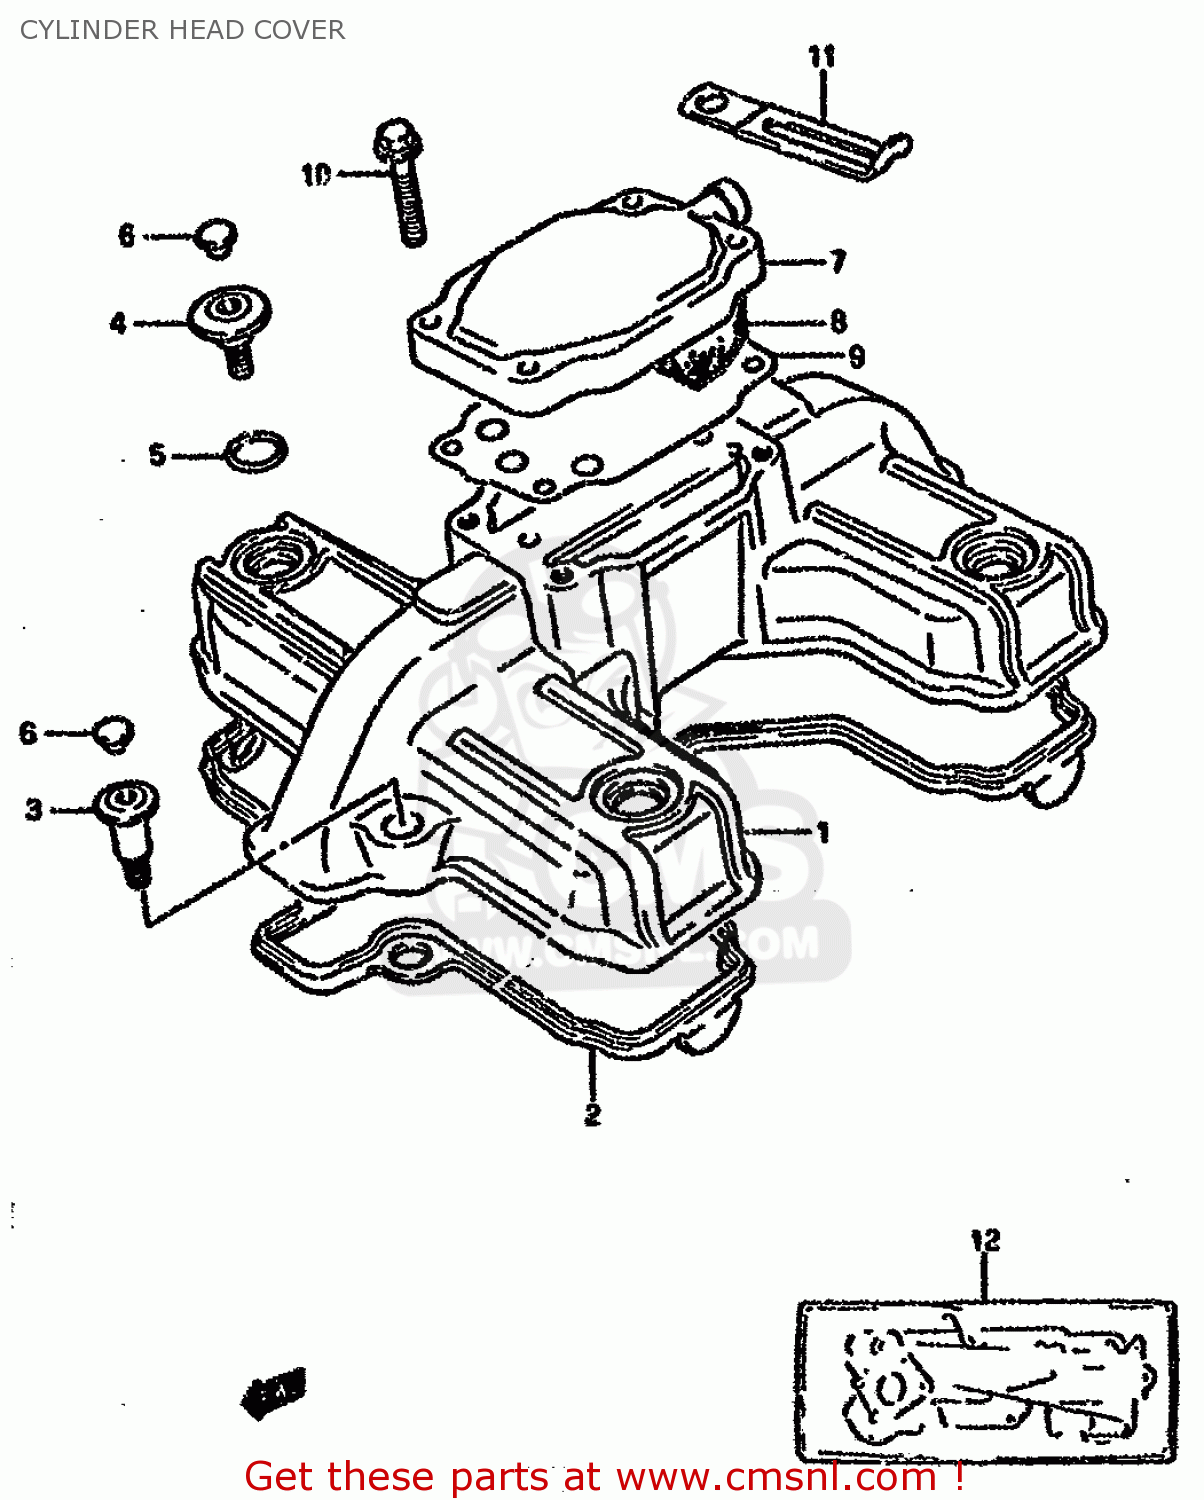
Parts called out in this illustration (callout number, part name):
1	COVER,CYLINDER HEAD
2	GASKET,CYLINDER HEAD COVER (NAS)
3	BOLT(7X19)
4	BOLT(7X5.5)
5	O RING(D:1.9,ID:14.5)
6	CAP(OD:10)
7	COVER,BREATHER
8	SEPARATOR,OIL BREATHER CO
9	GASKET,BREATHER COVER (NAS)
10	BOLT
11	CLAMP
12	GASKET SET (NAS)
